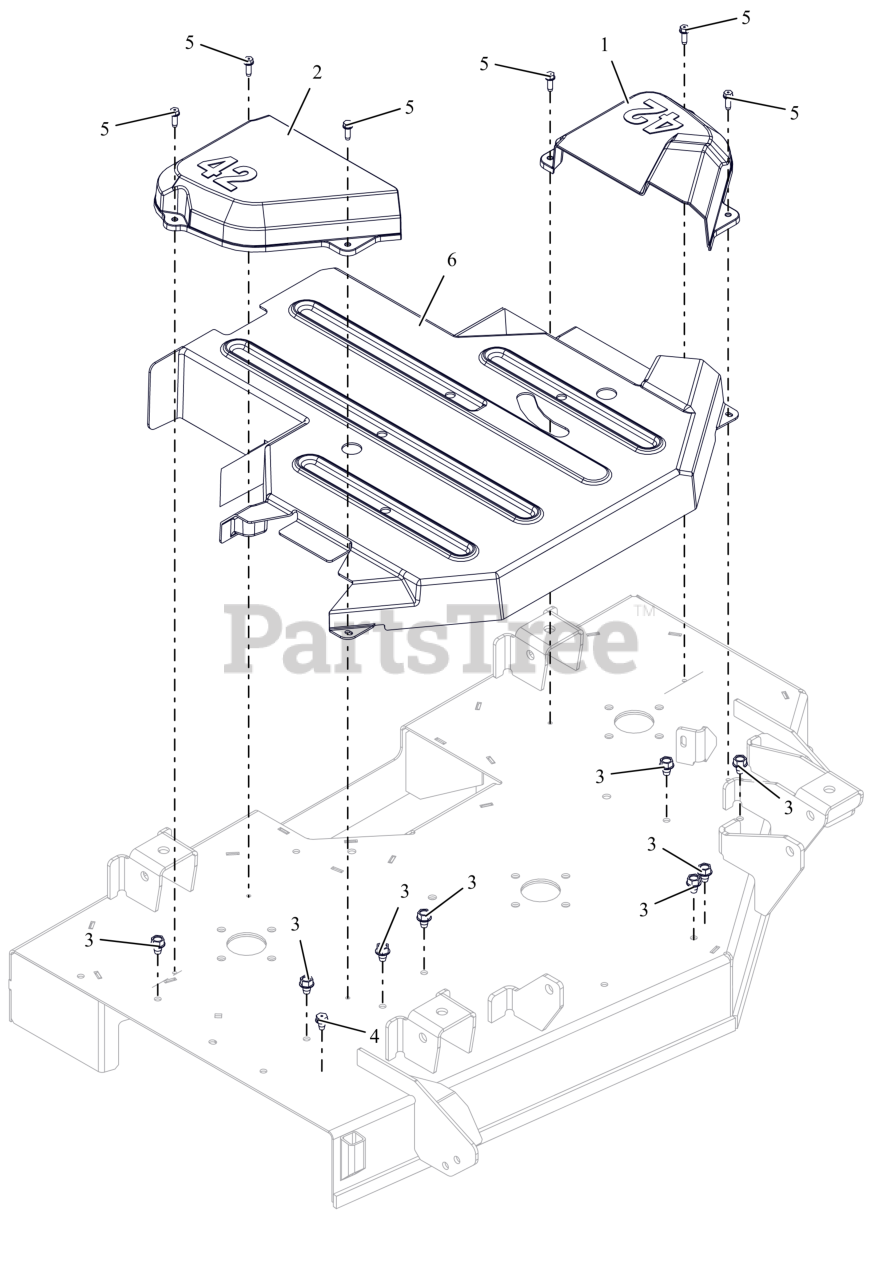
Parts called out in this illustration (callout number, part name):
1	COVER, BELT 42" LH
2	COVER, BELT 42" RH
3	SCR,TAP .375-16X.50 HWH TR ZCC
4	SCR,TAP .312-18X.50 HWH TR ZCC
5	SCR,TAP .25-20X.75 HWH TR ZCC
6	GUARD, IKON BELT-42" CE
